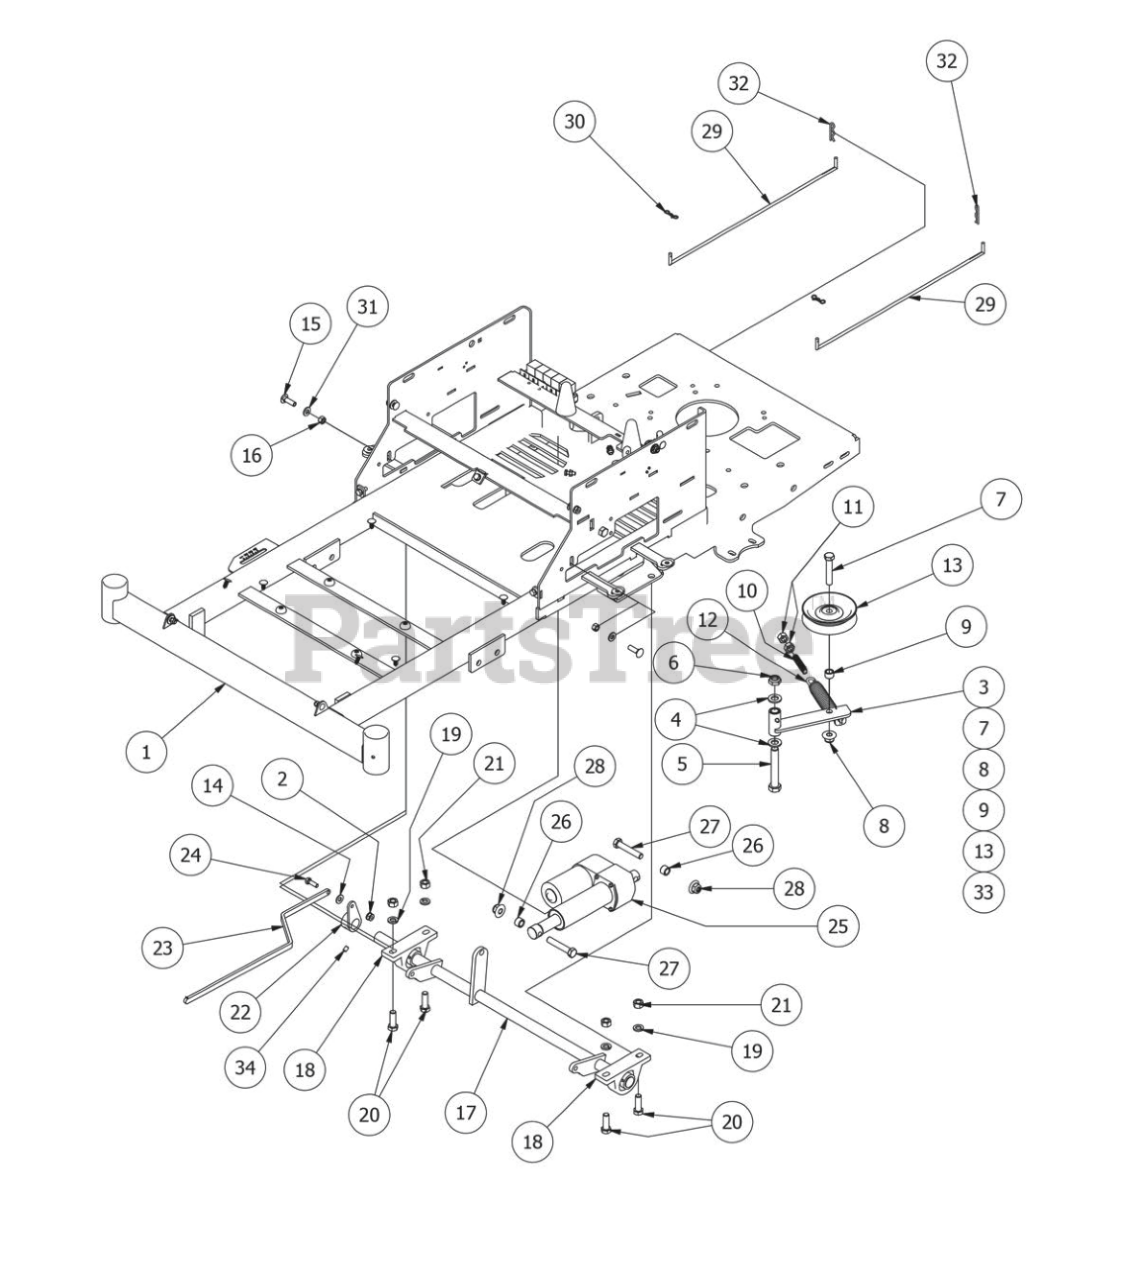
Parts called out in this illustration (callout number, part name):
1	ZT/CZT Frame 2013 Models
2	5/16-18 Nylon Flange Nut
3	Pump Idler Bracket
4	.635 ID Plastic Washer
5	5/8" x 4" Hex Bolt
6	5/8" Nylock (1/2 Jam)
7	1/2" x 2 3/4" Hex Bolt
8	1/2-13 Nylon Flange Nut-Orange
9	1/2 x 1/2 Spacer
10	All Thread-pump Idler Tensioner
11	1/2" Hex Nut
12	2009 Deck/Pump Idler Spring
13	4 3/4" Idler Pulley
14	.360 ID Plastic Washer
15	3/8" x 1 1/4" Carriage Bolt
16	3/8" Hex Nut
17	Actuator Bar-Transaxle
18	pillow block 2bolt sealmaster
19	1/2" Lock Washer
20	1/2" x 1 1/2" Hex Bolt
21	1/2" Hex Nut
22	Height Indicator Lever
23	Height Indicator Bar
24	5/16" x 1" Bolt
26	1/2 x 1/2 Spacer
27	1/2" x 2 3/4" Hex Bolt
28	1/2-13 Nylon Flange Nut-Orange
29	ZT Neutral level rod 2011
31	3/8" Flat Washer
32	Neutral Rod Clip
33	Pump Idler Assembly (Components 3,7,8,9,13)
34	5/16 Set Screw
